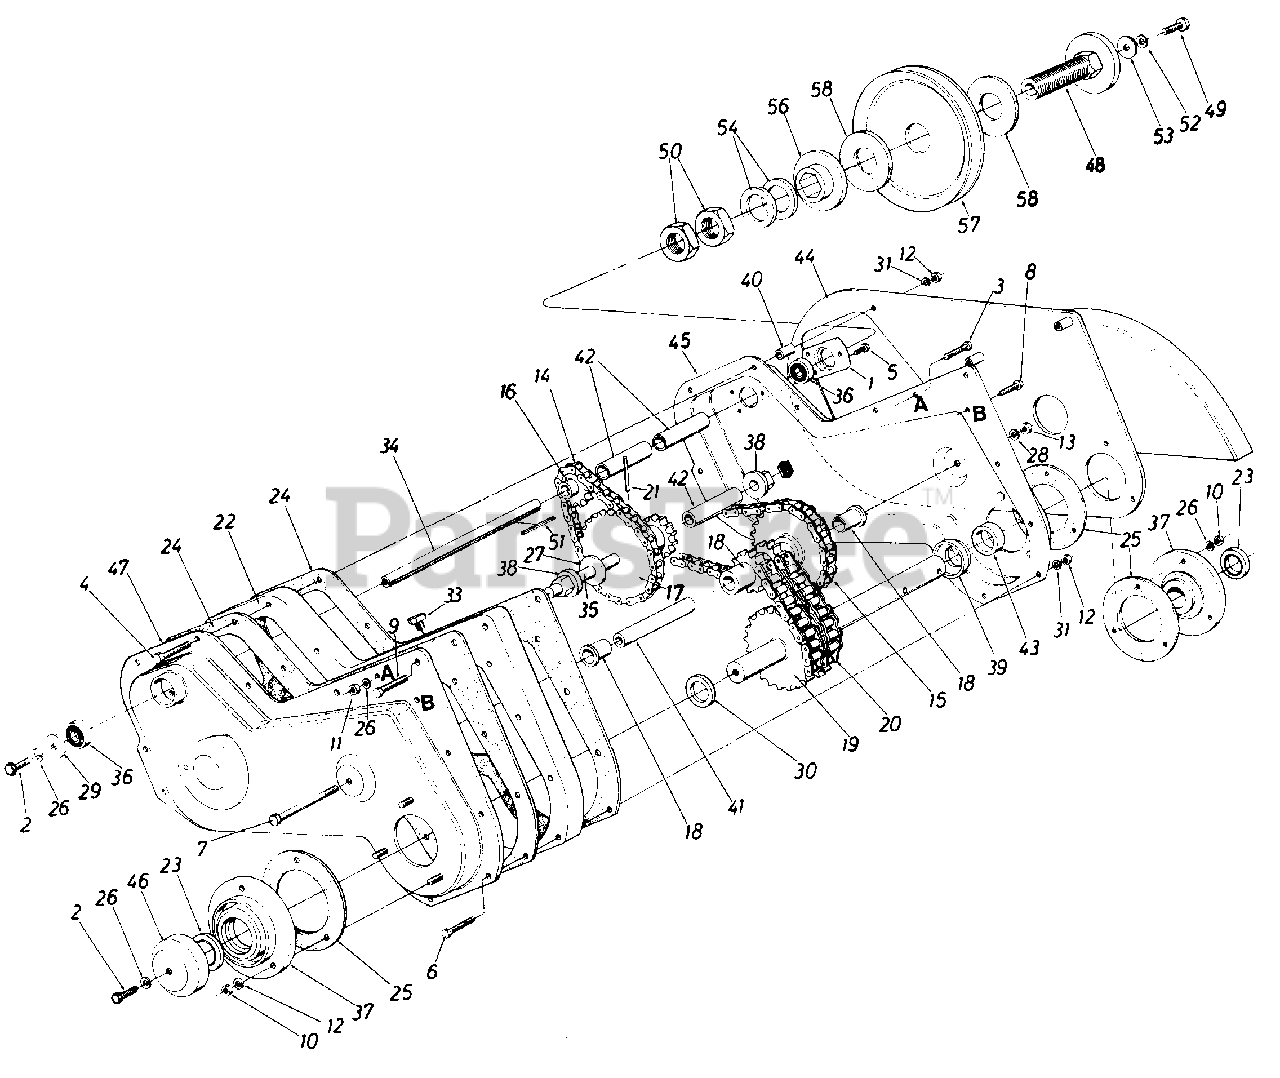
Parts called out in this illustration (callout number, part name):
1	Bearing Housing 1-3/8" Dia.
2	Hex Bolt 5/16-18 x .88" Lg. Spec.
3	Hex Bolt 5/16-18 x 1.50" Lg.*
4	Hex Bolt 1/4-20 x 2.75" Lg.*
5	Hex Wash. S-Tap. Scr. 1/4-20 x .50" Lg.
6	Hex Bolt i/4-20 x 1.50" Lg.*
7	Hex Bolt 3/8-16 x 4.5" Lg.
8	Hex Wash. Hd. Bolt 1/4-20 x 1.5" Lg.
9	Hex Wash. TT Tap Scr. 5/16-18 x 1.75" Lg.
10	HexCent. L.-Nut 5/16-18 Thd.
11	Hex Nut5/16-18 Thd.*
12	Hex Nut 1/4-2 Thd.*
13	Hex Nut 3/8-16 Thd.*
14	#41 Chain 1/2" Pitch x 34 Links- Endless
15	#42 Chain 1/2" Pitch x 48 Links- Endless
16	Sprocket 10 Tooth .500" Pitch
17	10 & 28 Teeth Sprocket Ass'y.
18	8-2 & 28 Sprocket Sleeve Ass'y.
19	18-2 Sprocket Shaft Ass'y.
20	#50-2 Chain 5/8" Pitch x 28 Links- Endless
21	Spring Pin Spir. 1/4" Dia. x 1.50" Lg.
22	Spacer Block - Tiller Housing
23	Oil Seal Double Lip-1-1/4" Dia.
24	Gasket for Tiller Housing
25	Gasket for Brg.-Housing
26	L.-Wash. 5/16" I.D.*
27	Fl.-Wash. .640" I.D. x 1.24" O.D.
28	L.-Wash. 3/8" I.D. Heavy Duty
29	Fl.-Wash. .344" I.D. x.1.125"
30	Special Washer
31	L.-Wash. 1/4" I.D.*
33	Vent Plug
34	Jack Shaft .525" I.D. x 7.78 " Lg.
35	Sprocket Shaft .63" D ia. x 5.0" Lg.
36	Ball Brg. .62" I.D. x 1.38" O.D.
37	Bearing Housing - 1-1/4"
38	Hex Flange Brg.
39	Spacer 1.25" I.D. x 2.0" O.D.
40	Spacer.28" I.D. x .62" O.D. x .90" Lg.
41	Spacer .38" I.D. x .62" O.D. x 3.44" Lg.
42	Spacer .62" I.D. x.88" O.D. x 1.56" Lg.
43	Spacer 1.25" I.D. x 1.62" O.D. x.50" Lg.
46	Dust Cap .320" Dia. Hole
49	Hex Bolt 5/16-18 x 1.25" Lg. Grade 5
50	Hex Jam Nut 1.0-14 x 28 Thd.
51	Sq. Key 3/16 x 1.50" Lg.
52	L.-Wash. 5/16" I.D.*
53	Fl.-Wash. .344" I.D. x 1.125"O.D.
54	Spring Bell Wash. 1.0" I.D. x 2.0" O.D.
56	F loating Disc 3-1/4" O. D. x 1.0" I.D.
57	5/8 V-Pulley 1.50" I.D. x 6.50"
58	Friction Pad 3-1/4" O.D. x 1-3/8" I.D.
